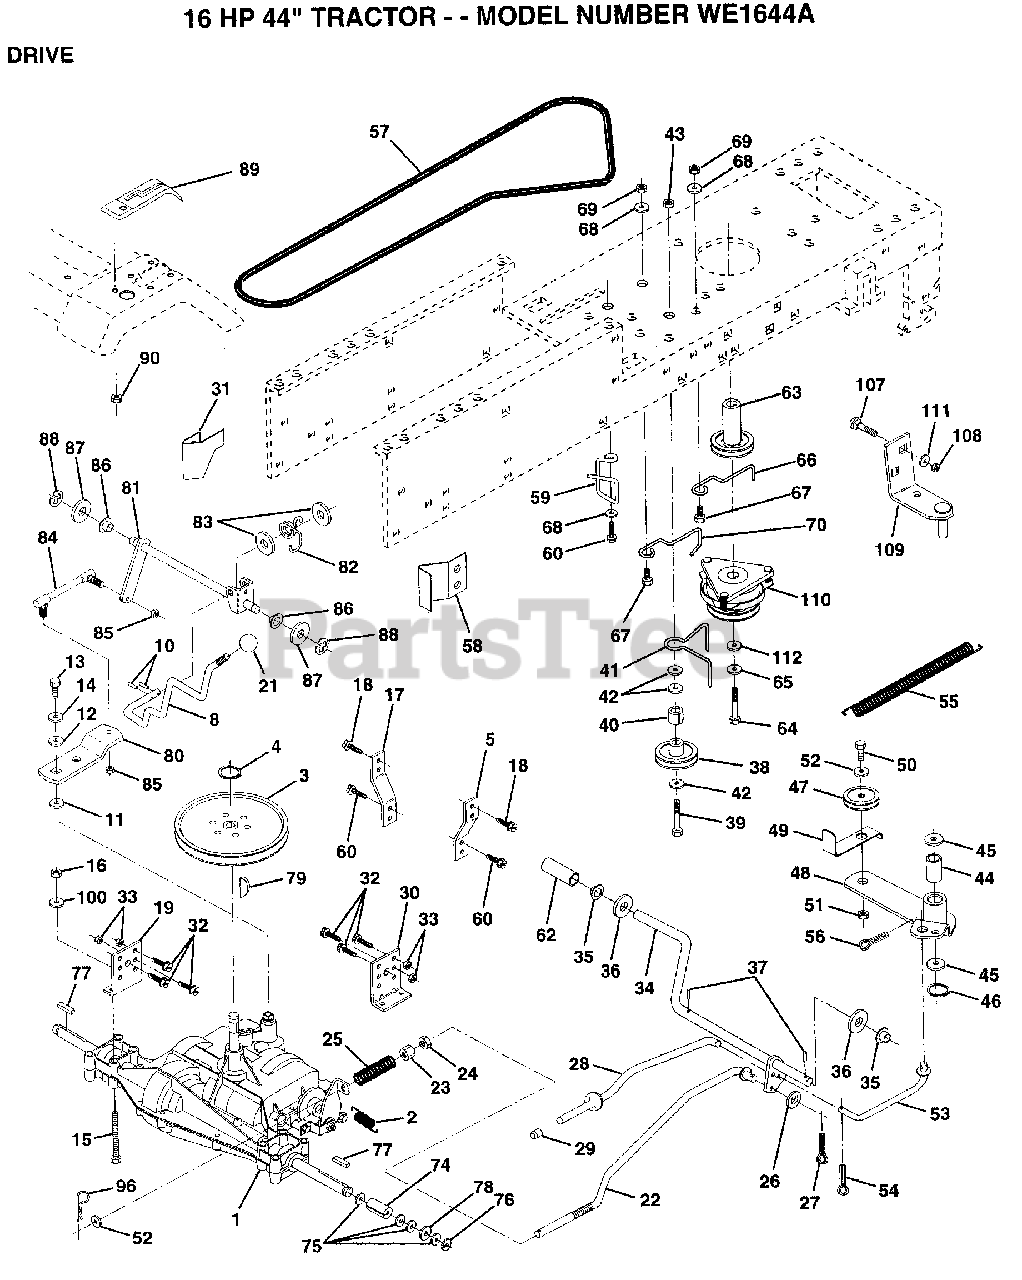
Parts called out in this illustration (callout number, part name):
1	TRANSAX. PRLES.
3	PULLEY TRANSAXLE
4	RING
5	STRAP TORQUE
10	PIN COTTER 1/8
11	WASH-SHFT PLT LT
12	WASHER
14	WASHER PM
15	BOLT HEX
17	STRAP TORQUE
18	SCREW
19	BRKT TRANS LH
21	KNOB T (1/2-HOLE)
22	ROD BRAKE
23	NUT
24	NUT
25	"SPRING,ROD BRAKE"
27	COTTER PIN
28	BRAKE PARK ROD
29	PLUNGER CAP T
30	BRKT TRANS RH
31	KEEPER BELT LH
35	NYLON BEARING
36	WASHER LT
38	PULLEY.IDLER.FLAT
39	BOLT
40	SPACER T
41	BELT KEEPER LT
42	WASHER
43	NUT
44	"LY, BEARING"
45	WASHER LT
46	KLIP RING
48	ARM IDLER
49	RETAIN BELT
52	WASHER
53	"LINK, CLUTCH T"
55	"SPRING, RETURN LT"
57	BELT.GRDRV.94.75
58	"KEEPER,BELT RH"
59	KEEPER BELT CNTSP
60	SCREW
62	PEDAL COVER T
63	PULLEY ENGINE
65	LOCKWASHER
66	KEEPER BELT ENGLH
67	BOLT
68	WASHER
70	"KEEPER,BLT ENG LT"
74	SPACER HYT
75	WASHER
76	E RING HYT
77	SQ KEY STD
80	"ARM,SHIFT"
81	"SHAFT,SHIFTER"
82	"SPRING,TORSION"
83	WASHER
84	"ROD,TIE "
85	NUT 1/4-28
86	BUSHING
87	WASHER D
88	KLIP RING
89	CONSOLE SHIFTER
90	NUT
96	RETAINER M
100	WASHER M
102	CLIP T
107	BOLT
109	BRACKET.ASM.MTG
111	WASHER T
112	WASHER
